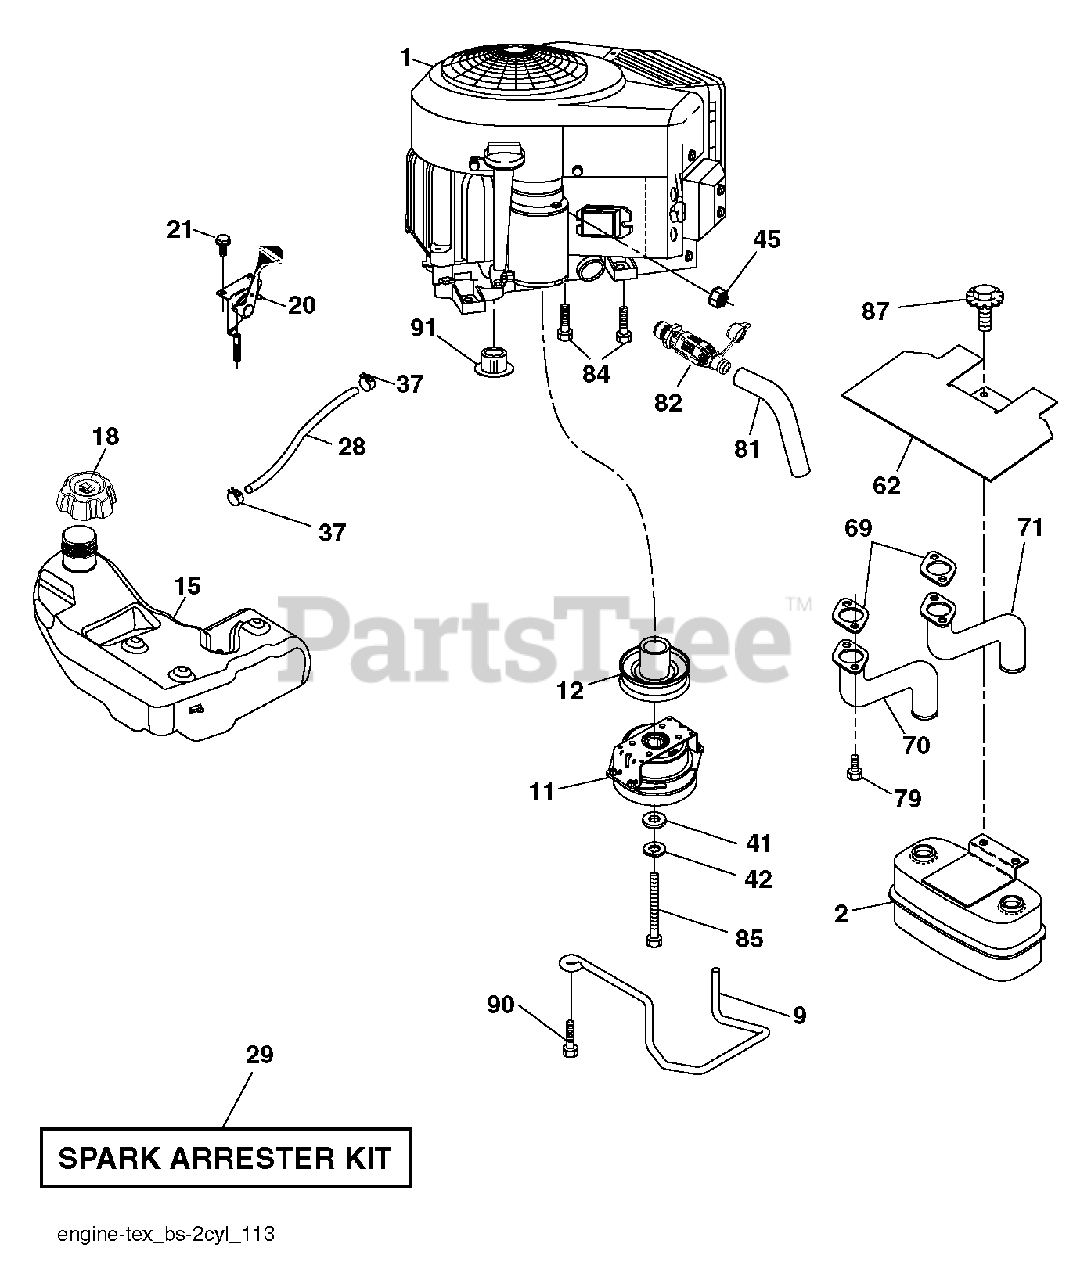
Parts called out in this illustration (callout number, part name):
2	MUFFLER.ASM.TWN.EXTNDED.DFLCTR
9	KEEPER BELT ENGINE
11	CLUTCH.OGURA.5.0PD.GT1.5A-EH01
12	PULLEY ENGINE
15	TANK.FUEL.4GAL
18	CAP.ASSY.FUEL.3".N-EPA.GRY.498
20	CONTROL.TH/CK.COBRA.B&S.TWN.
21	SCREW.#10 X 0.750.BOS
28	REPL BY 532 00 85-43
29	KIT.SPARK ARRESTOR 794945 B&S
37	HOSE CLAMP
42	LOCKWASHER
45	NUT
62	SHIELD.HEAT.MUFFLER
69	GASKET.MUFFLER
70	EXHAUST.TUBE.LH.BS/TWIN
71	EXHAUST.TUBE.RH.B&S.TWIN.INTEK
79	SCREW.SOCKET.HEAD.5/16-18
81	TUBE, DRAIN OIL ASM.
82	VALUE.OIL.DRAIN
84	SCREW.3/8-16
85	BOLT.HEX.7/16-20X3.0XGR5
87	BOLT, 5/16-18 X 1 3/4
90	SCREW 3/8-16X1
91	BUSHING.1.375OD
